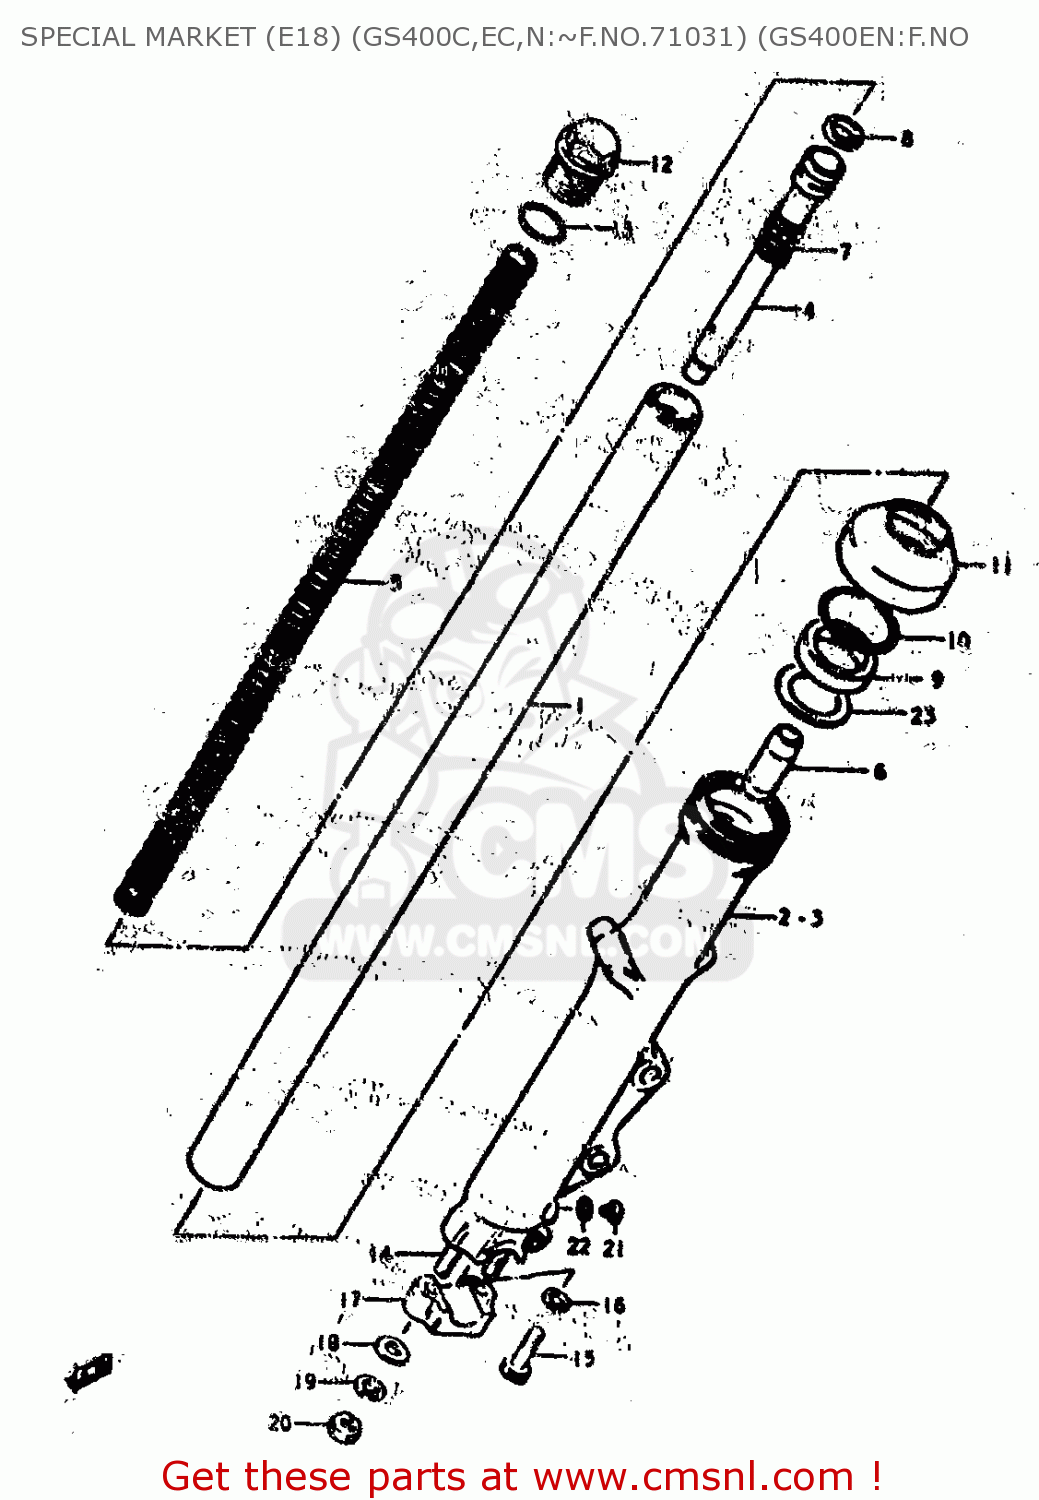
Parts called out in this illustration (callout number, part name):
1	TUBE,INNER
2	TUBE,OUTER,LEFT
3	TUBE,OUTER,RIGHT
4	CYLINDER,FRONT FORK
5	SPRING
6	PIECE,OIL LOCK
7	SPRING,REBOUND
8	RING,PISTON
9	OIL SEAL,FRONT FORK
10	CIRCLIP,FORK OIL SEAL
11	BOOT
12	BOLT
13	O RING
14	STUD 8X25
15	BOLT
16	GASKET (NAS)
17	HOLDER,AXLE
18	WASHER
19	LOCK WASHER
20	NUT
21	SCREW
22	GASKET (NAS)
